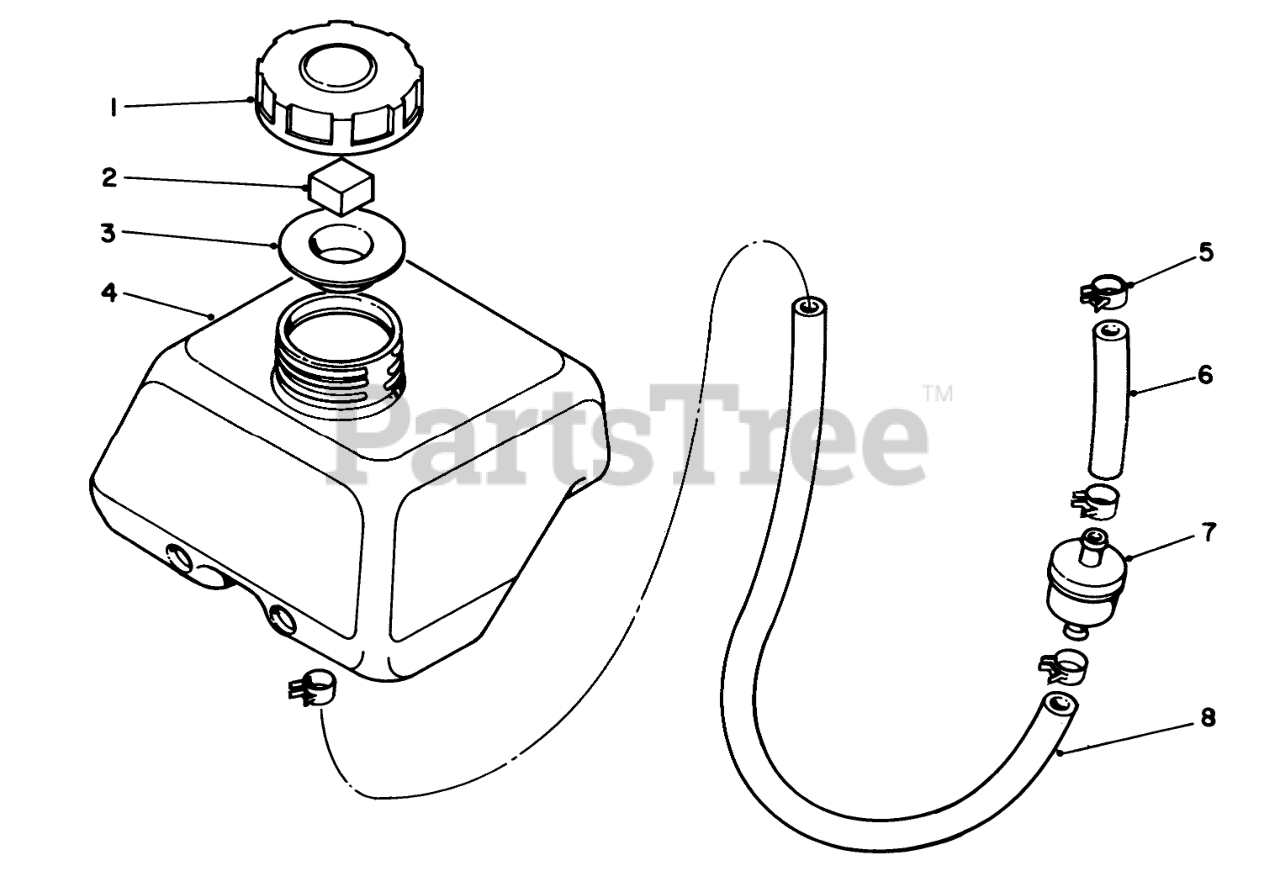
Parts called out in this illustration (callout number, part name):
1	Fuel Cap Assembly (Incl. Ref. #2 & 3)
2	Gasket-Inner
3	Gasket-Outer
4	Tank-Fuel
7	FUEL FILTER
